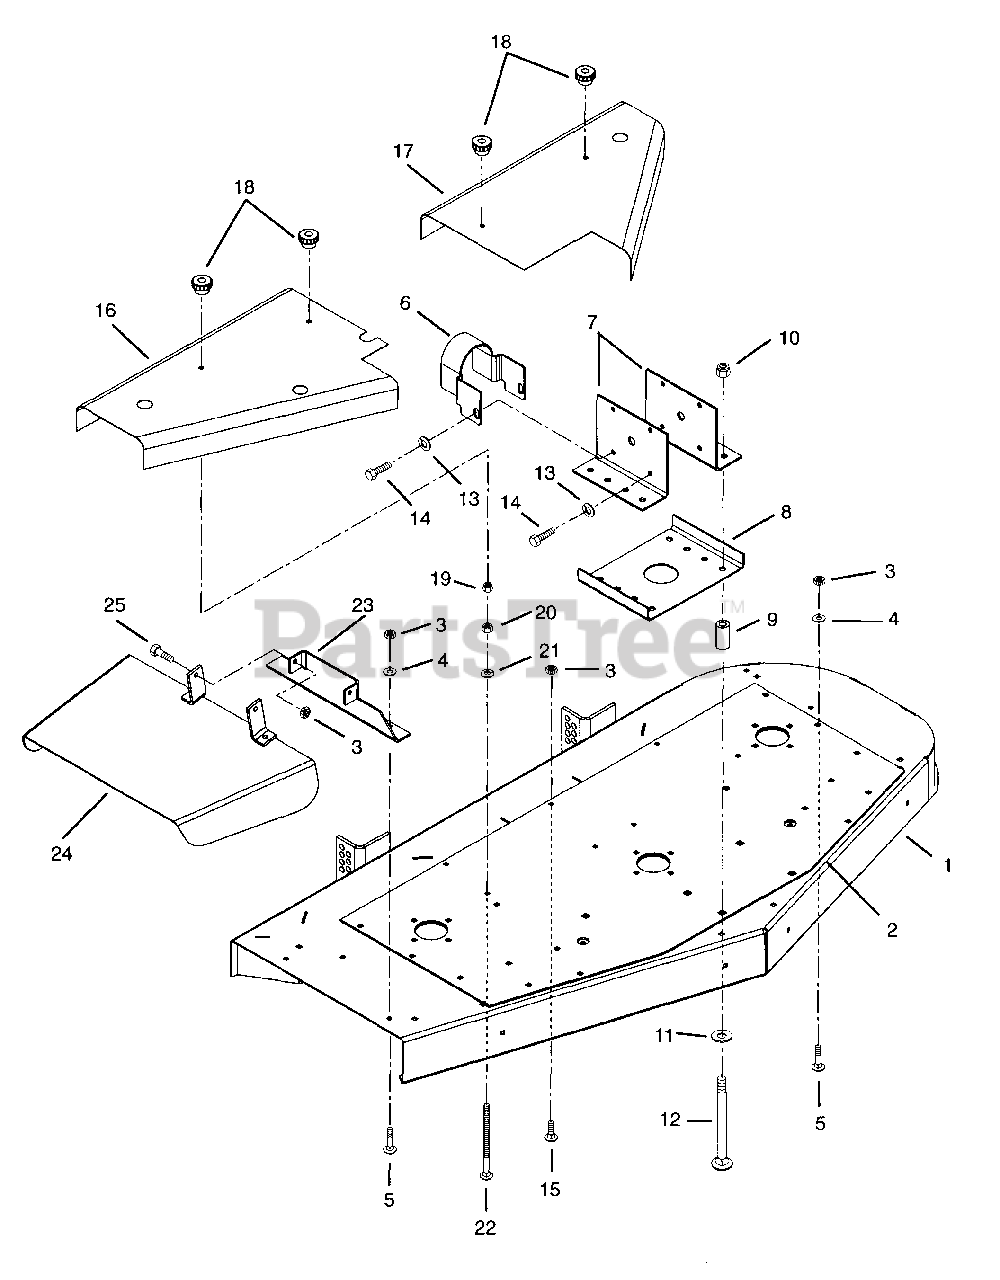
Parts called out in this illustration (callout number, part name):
1	Weldment, Deck 60" Mower PM350
2	Plate, 60" Deck Reinforcement
3	Nut-Locking-Nylon .375-16 Grade 2
4	Washer-Flat-Steel .406 x .812 x .065
5	Bolt-Round Head Square Neck .38-16 x 1.0
6	Shield U-Joint
7	Bracket, Gearbox Mounting
8	Plate, Support
9	Spacer.562 x 1.00 x 2.00
10	Nut-Locking-Nylon .50-13 Grade 5
11	Washer-Flat-Steel .531 x 1.062 x .095
12	Bolt-Hex .50-13 x 3.75
13	Washer-Lock .375 x .094
14	Bolt-Hex .380-16 x .875
15	Bolt-Round Head Square Neck .31-18 x .62
16	Cover, Mower Belt Right Hand
17	Cover, Mower Belt Left Hand
18	Knob
19	Nut-Locking-Nylon .312-18 Grade 2
20	Nut-Hex .312-18 Grade 2
21	Washer-Lock .313 x .078
22	Bolt-Round Head Square Neck .31-18 x 3.50
23	Bracket, Discharge
24	Weldment, Discharge Chute
25	Bolt-Hex .38-16 x 1.00 Grade 5
